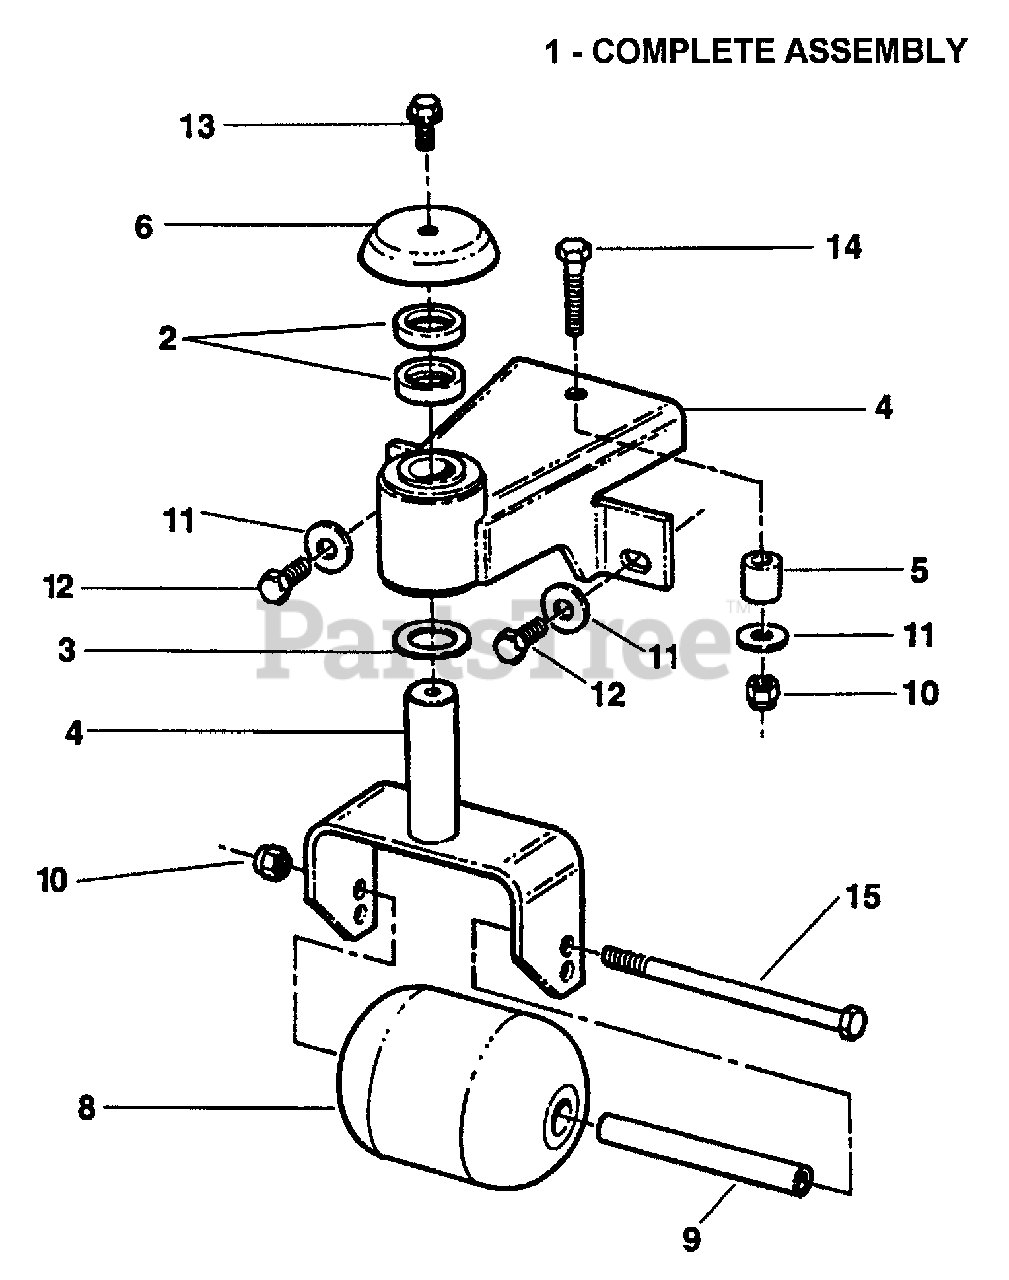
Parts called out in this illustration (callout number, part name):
1	ASSEMBLY, Roller
2	SPACER, 1" x 1 3/8 x .30" (PM)
3	BUSHING, 1" Machine
4	CASTER, Gage Wheel (Weldment)
5	SPACER, 3/8 x .75"
6	CAP, Caster Shaft
8	ROLLER, 3 3/4 x 4 13/16" Nylon
9	TUBE, Axle
10	NUT, 3/8-16 HEX NYLON LOCK
11	WASHER, 3/8" USS
12	BOLT, 3/8-16 X 1" GD5 CZ
13	SCREW, 5/16-18 x 3/4" Hex Washer Head, Self-Tapping
14	SCREW, 3/8-16 x 1 3/4" Hex Head Cap
15	BOLT, 3/8-16 X 6" GD5 CZ
